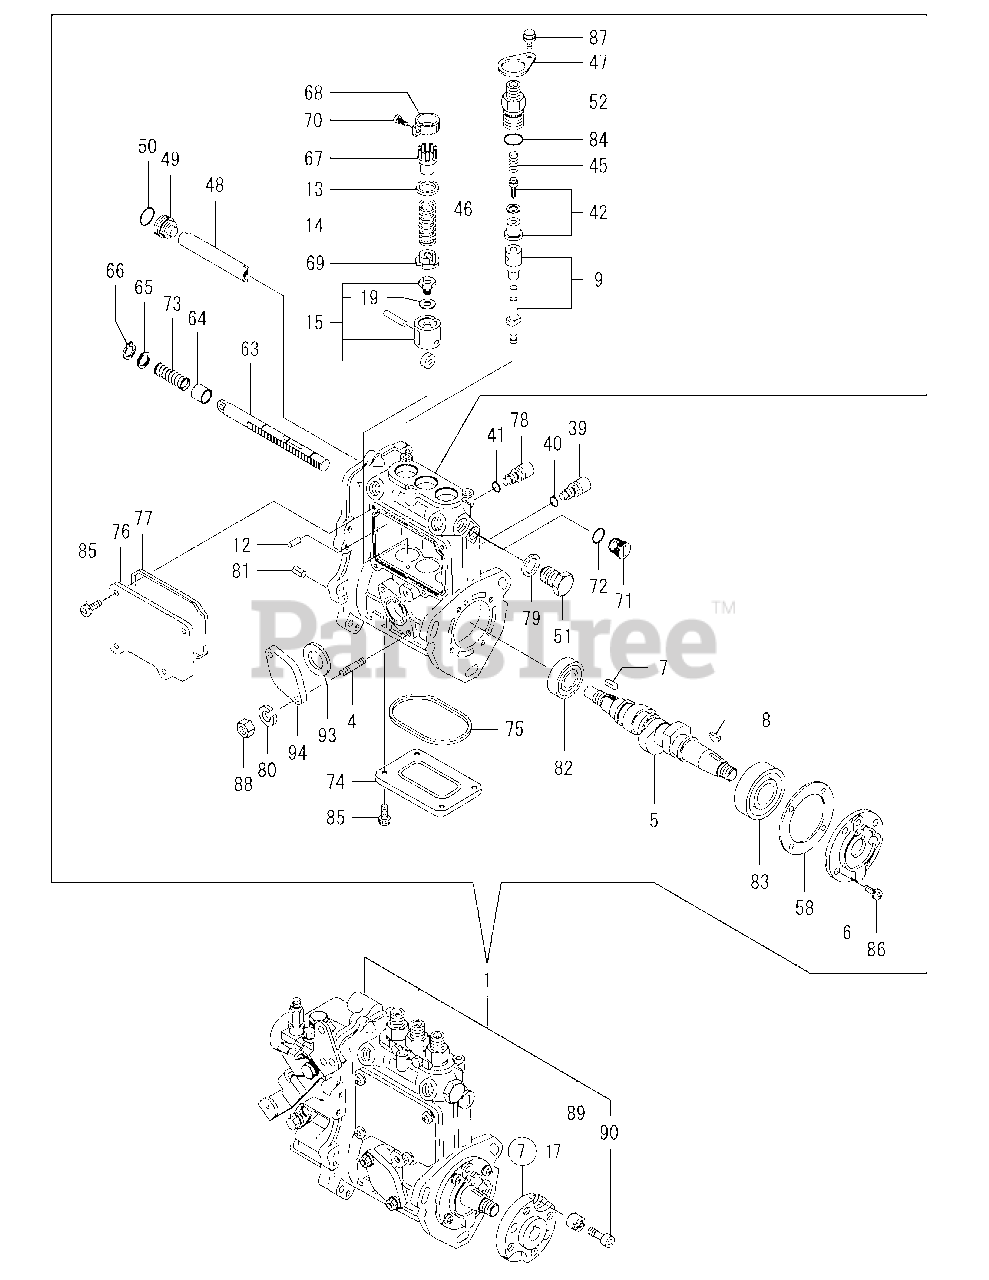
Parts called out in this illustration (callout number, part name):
1	FIE ASSY (3TNV72-YUKS)
4	STUD, FEED PUMP
6	SUPPORT,BEARING
12	PIN, BARREL LOCKING
14	SPRING, PLUNGER
42	VALVE ASSY, DELIVERY
45	SPRING, DELIVERY
46	GASKET, DELIVERY
52	VALVE ASSY, DELIVERY
58	SHIM SET, ADJUSTING
65	SPACER, AUX. SPRING
67	PINION, CONTROL
69	RECEIVER, SPRING
76	COVER, BODY SIDE
79	SEAL WASHER 16S
80	SPRING WASHER 6
81	SPRING PIN 5X10
83	BALL BEARING
87	BOLT M 5X 10 PLATED
89	COLLAR. FIC FIX
90	BOLT, FIXATION
